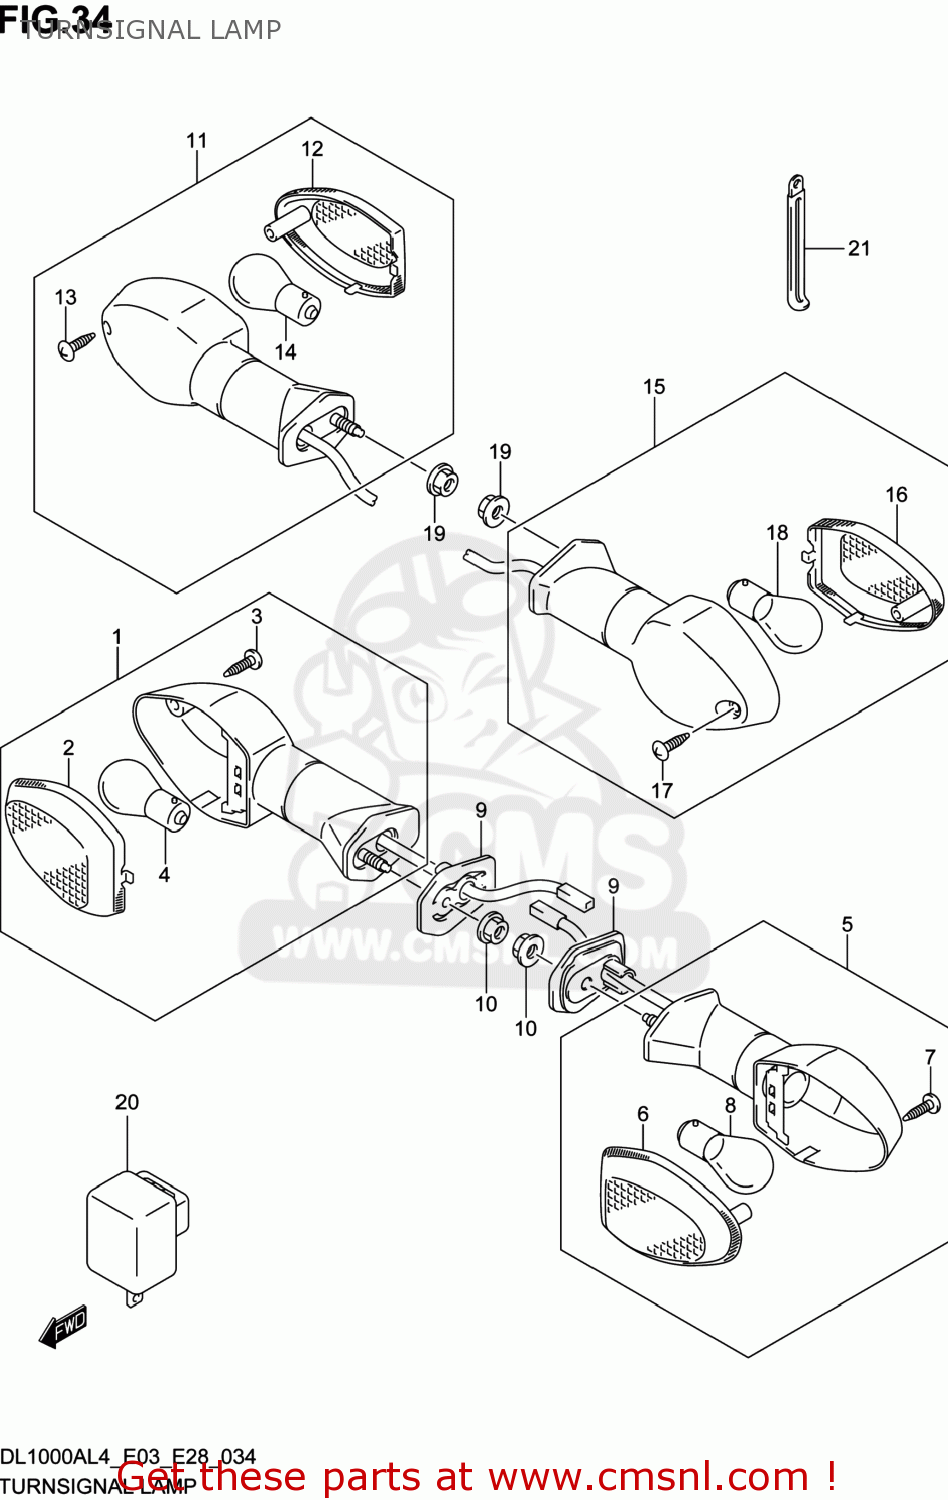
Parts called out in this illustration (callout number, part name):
1	LAMP ASSY,FR TURNSIGNAL,R
2	LENS
3	SCREW
4	BULB(12V21W,AMBER)
5	LAMP ASSY,FR TURNSIGNAL,L
6	LENS
7	SCREW
8	BULB(12V21W,AMBER)
9	PLATE,FR TURNSIGNAL
10	NUT
11	LAMP ASSY,RR TURNSIGNAL,R
12	LENS
13	SCREW
14	BULB(12V21W,AMBER)
15	LAMP ASSY,RR TURNSIGNAL,L
16	LENS
17	SCREW
18	BULB(12V21W,AMBER)
19	NUT
20	RELAY ASSY,TURNSIGNAL
21	CLAMP(L:45)
